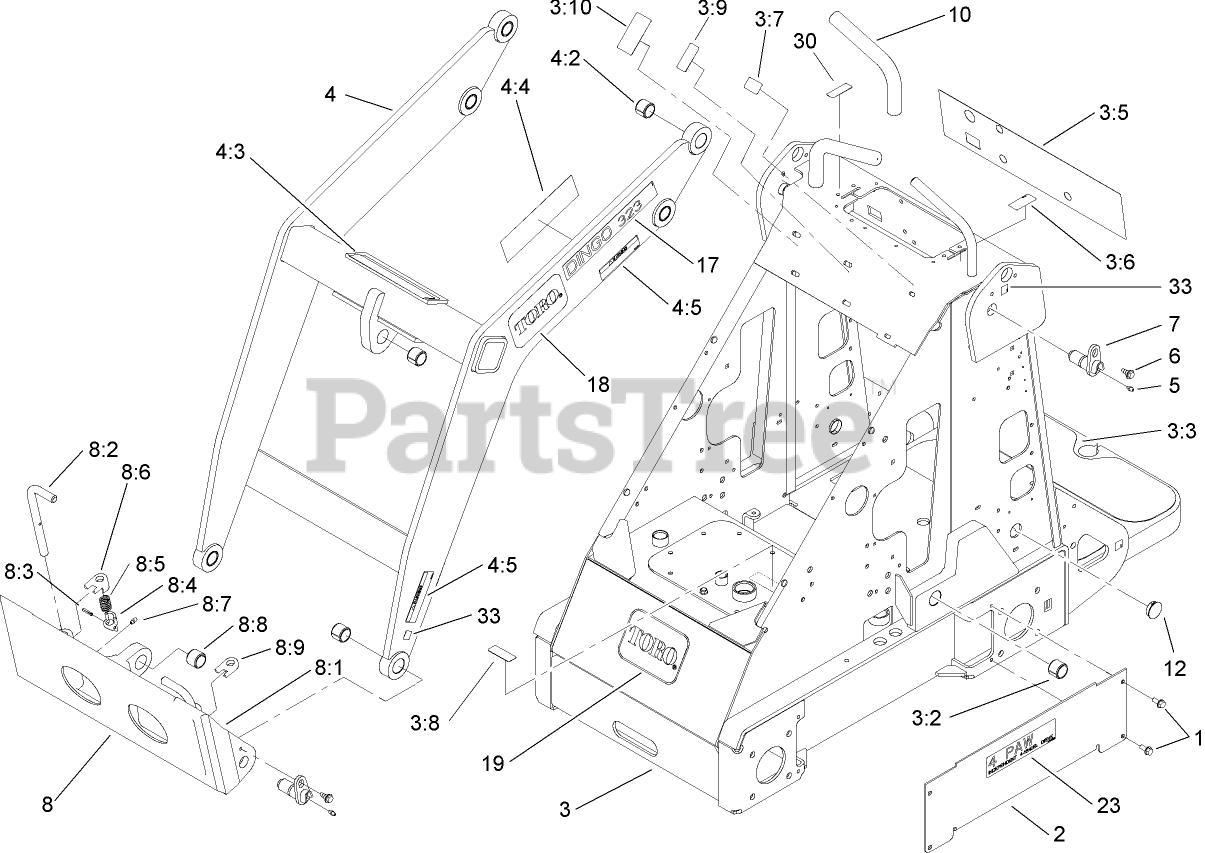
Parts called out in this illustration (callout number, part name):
1	SCREW-HWHTF
2	COVER-HOSE
3	FRAME ASM
3:2	BUSHING-TENSION
3:3	TREAD-FOOT
3:5	DECAL-PANEL, CONTROL
3:6	DECAL-THROTTLE
3:7	DECAL-LIMITER, SPEED
3:8	DECAL-OIL, HYD
3:9	DECAL-SELECTOR
3:10	DECAL-POWER, AUXILIARY
4	LOADER ASM
4:2	BUSHING-TENSION
4:3	DECAL-CAUTION
4:4	DECAL-DANGER
4:5	DECAL-PINCH
5	FITTING-GREASE
6	BOLT-SHOULDER
7	PIN-PIVOT
8	QUICK ATTACH ASM
8:1	MOUNT-ATTACH, QUICK
8:2	PIN-LOCKING
8:3	PIN-GROOVED
8:5	SPRING-COMPRESSION
8:6	STOP-RH
8:7	FITTING-GREASE
8:8	BUSHING-TENSION
8:9	STOP-LH
10	GRIP-CUSHION
12	PLUG-HOLE
17	Decal
18	DECAL
19	DECAL
30	DECAL-CHOKE
33	DECAL-POINT, LIFT
